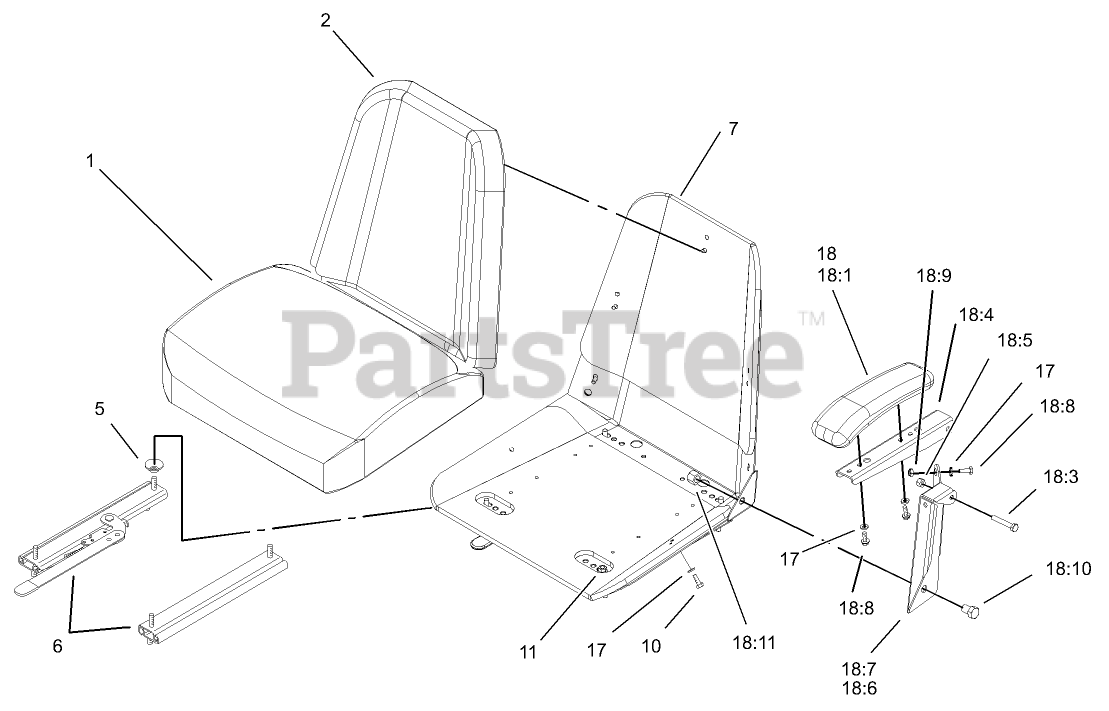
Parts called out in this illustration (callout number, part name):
1	CUSHION-SEAT, BOTTOM
2	CUSHION-SEAT, BACK
5	SPACER-TRACK
6	TRACK-SEAT
7	FRAME-SEAT
10	SCREW-HH
11	NUT-HF
17	WASHER-FLAT
18	ARMREST KIT
18:1	CUSHION-ARMREST
18:3	SCREW-HH
18:4	CHANNEL-ARMREST
18:5	NUT-HEX, SIDE DEFORM
18:7	Bracket-Armrest, LH
18:8	SCREW-HH
18:9	NUT-LOCK, NI
18:10	SCREW-HH
18:11	NUT-HEX
